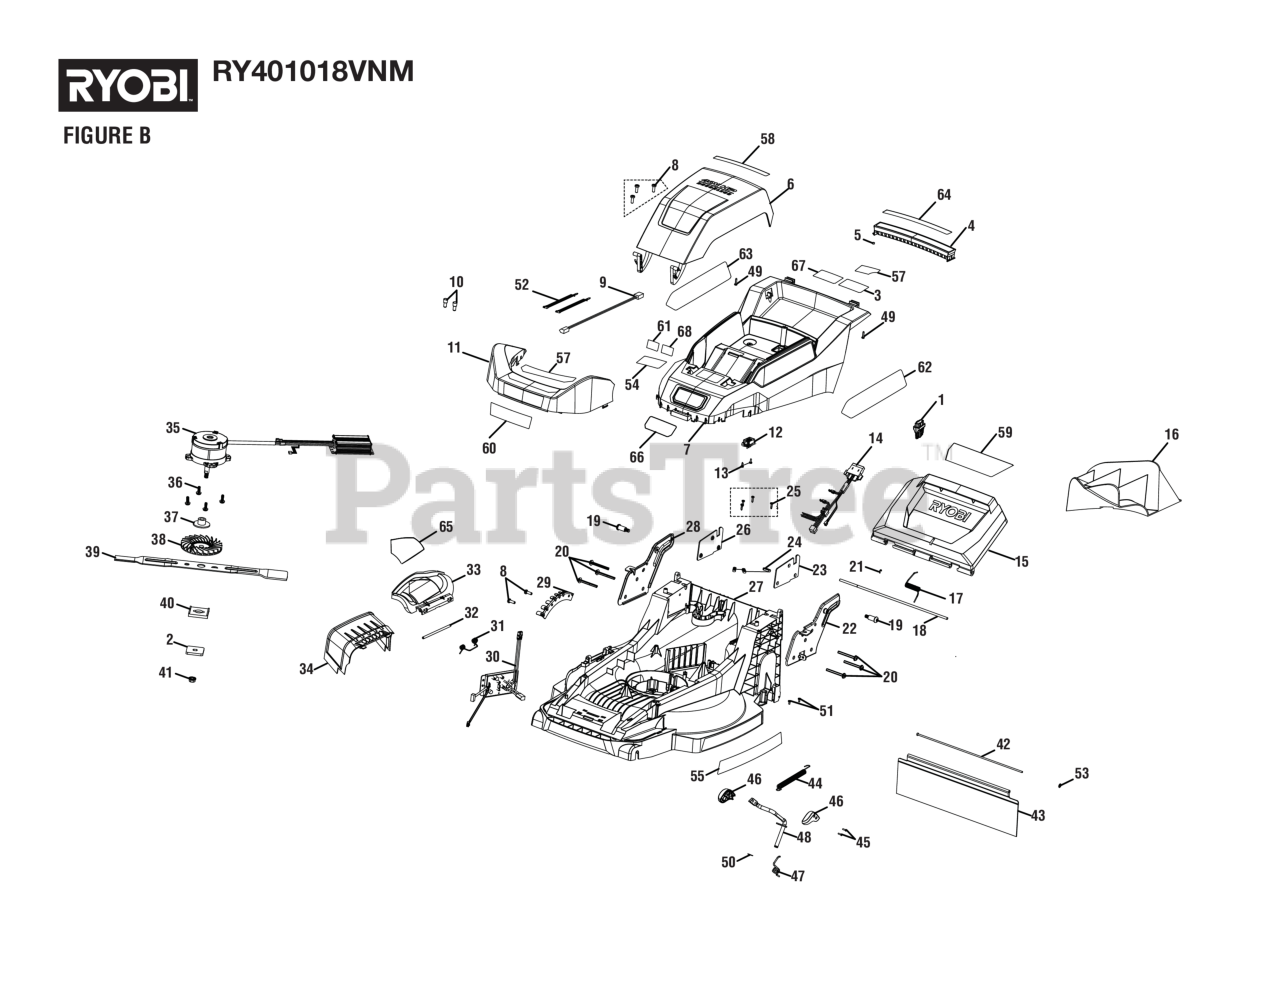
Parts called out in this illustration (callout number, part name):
1	Start Key
2	Blade Spacer Metal Plate
3	Start Key Label (Spanish)
4	Carry Handle
5	Door Magnet
6	Battery Cover
7	Top Housing
8	Screw (1/4-15 x 3/4 in., T30 Torx Pan Hd.)
9	Inner Wire with Connector Between Transmission and Circuit Board Assembly
10	Close-End Connector
11	Front Fender
12	Key Holder
13	Screw (M4.2 x 12 mm, T20 Torx Pan Hd.)
14	BATTERY HOLDER AND WIRE ASSEMBLY
15	Rear Door
16	Mulching Plug
17	Rear Door Torsion Spring
18	Rear Door Shaft
19	Screw w/Shoulder (M8 x 35.7 mm, T45 Torx Pan Hd.)
20	Screw (M6 x 64 mm, T30 Torx Pan Hd.)
22	Handle Bracket (Left)
23	Handle Bracket Nut Plate
24	Wire Press Plate
25	Screw (M4 x 16 mm, T20 Torx Pan Hd.).
26	Right Handle Bracket Nut
27	Deck
28	Right Handle Bracket
29	Height Adjustment Plate
30	Drive Motor Controller 40v Self-Propelled Mower
31	Side Discharge Cover Torsion Spring
32	Side Discharge Shaft Cover
33	Side Discharge
34	Side Discharge Chute
35	Mower Controller Assembly
36	Screw (M6 x 1 mm, T30 Torx Pan Hd.)
37	Motor Shaft Bushing
38	Motor Fan Blade Adapter
39	20 in. Blade
40	Plastic Blade Spacer
41	Blade Nut (M10 x 1.25, Hex Flange Hd.)
42	Trailing Sheet Rod
43	Trailing Sheet
44	Retention Spring
45	Screw (M3 x 12 mm, Pan Hd.)
46	Height Adjustment Knob Assembly
47	Height Adjustmen Rod Torsion Spring
48	Height Adjustment Rod
49	Screw (M4 x 18 mm, T20 Torx Pan Hd.)
51	Screw (M4 x 8 mm, T25 Torx Pan Hd. T.F.)
52	NYLON CABLE TIE
53	Retaining Ring
54	Data Label - TUV
54	Data Label - UL
55	Deck Side Label
56	QR Code Label
57	Push Front Bumper Label
58	Icon Label
59	Danger Label (Bagger Door)
60	3-In-1 Front Label
61	Battery Storage Label
62	Brushless Logo Label
63	Brushless Logo Label
64	Carry Handle Accent Label
65	Danger Label (No Hands/Feet)
66	Logo Label
67	Battery Wet Conditions Label
68	Start Key Label (Spanish)
